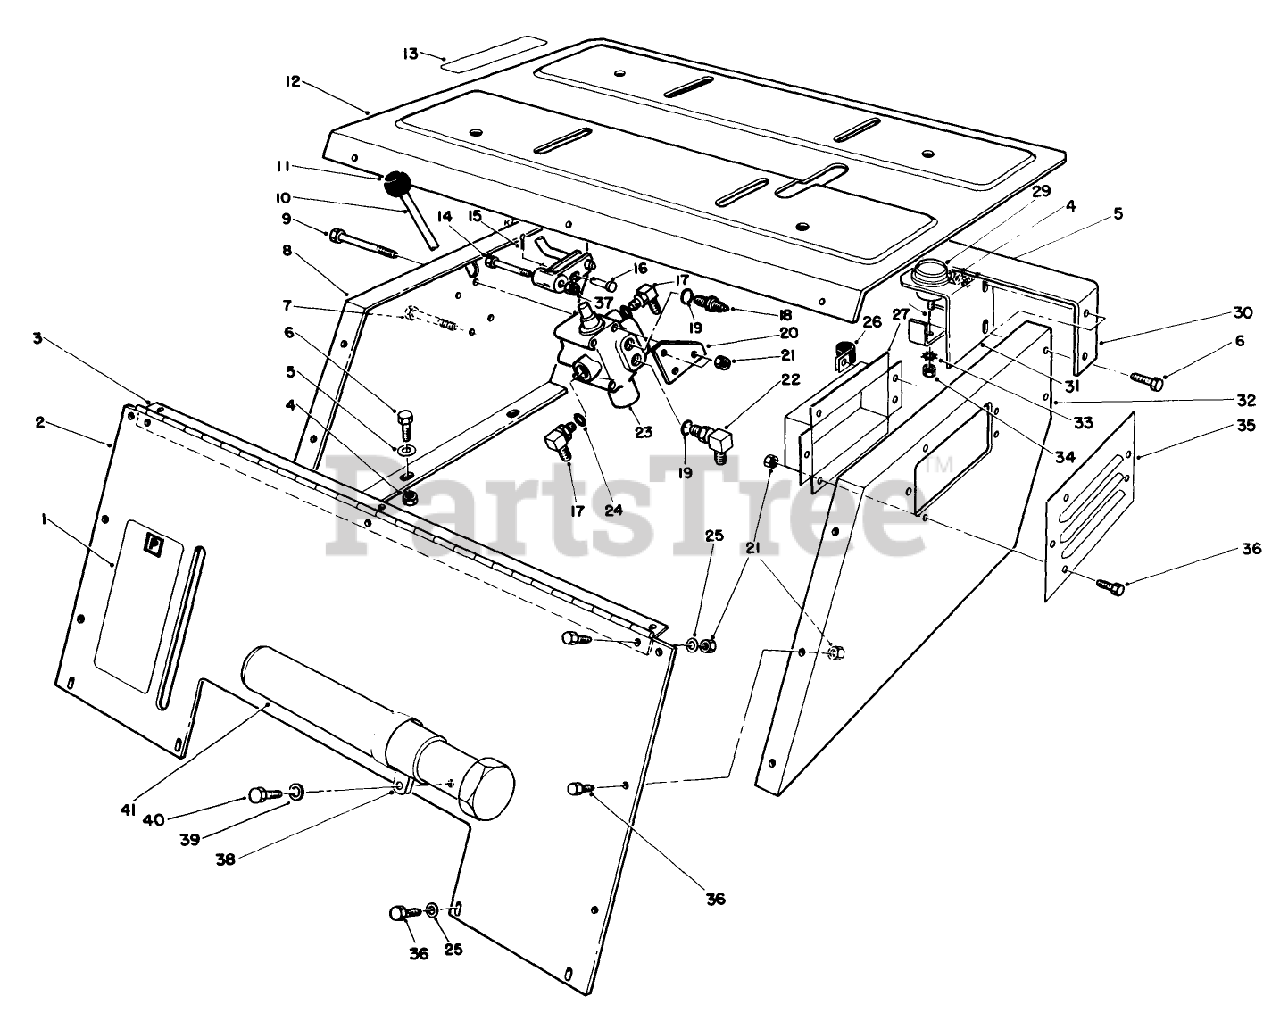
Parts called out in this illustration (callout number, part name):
1	PARK BRAKE DECAL
2	Support-Seat, Front
3	Hinge-Seat
4	NUT-LOCK, NI
5	WASHER-PLAIN
6	SCREW-HH
7	SCREW-HH
8	Support-Seat RH.
9	SCREW-HH
10	Lever-Valve
12	SEAT PLATE R
13	LIFT CONTROL DECAL
14	BOLT-WHEEL
15	PIN-COTTER
16	PIN-CLEVIS
17	FITTING-HYD, 90 DEG
18	FITTING-STRAIGHT
19	O-RING
20	LEVER BRACKET
21	NUT-LOCK, NI
22	FITTING-ELBOW, 90
23	VALVE ASM
24	O-RING
25	WASHER-FLAT
26	CLAMP
27	AIR CHAMBER WA B
28	BRACKET F/W
29	Hour Meter
30	Support-Hood
31	HR.METER BRKT. R
32	LH SEAT SUPPORT R
33	WASHER-LOCK, INT
34	NUT-HEX
35	AIR CHAMBER COVER R
36	SCREW-HH
37	NUT-LOCK, NI
38	CLAMP-R
39	WASHER-FLAT
40	SCREW-HWHTF
41	TUBE-MANUAL
